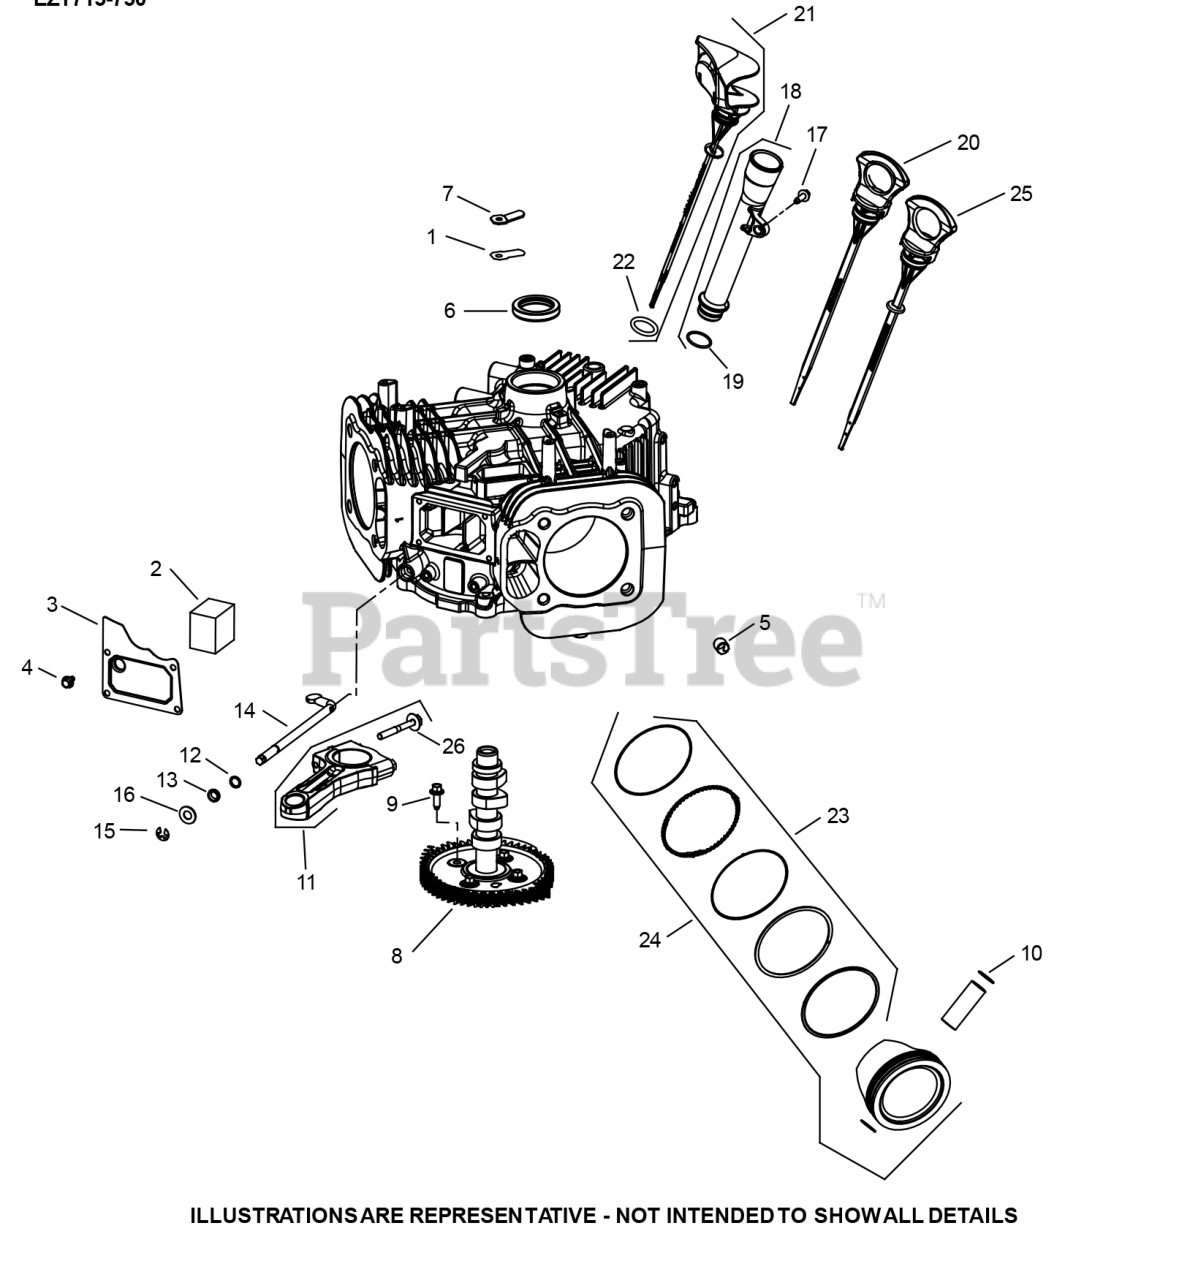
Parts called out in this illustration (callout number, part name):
1	BREATHER REED
2	BREATHER FILTER
3	COVER-BREATHER FILTE
5	PIN-SPLIT DOWEL
7	RETAINER-BREATHER
8	CAMSHAFT ASSEMBLY
10	RETAINER-PISTON
11	CONNECTING ROD ASSEMBLY
12	WASHER-1/4 FLAT
14	CROSS CARBURETOR SHAFT KIT
15	GOVERNOR SHAFT RETAINER CLIP
16	WASHER-9MM FLAT
17	THREAD FORMING SCREW
18	DIPSTICK TUBE
22	O-RING DIPSTICK
23	RING SET(STD)STYLE B-1.2mm Tp RING THICK
23	RING SET(.08)STYLE B-1.2mm Tp RING THICK
23	RING SET(.25)STYLE B-1.2mm Tp RING THICK
23	RING SET(.50)STYLE B-1.2mm Tp RING THICK
24	PISTON KIT (STD)
24	PISTON KIT (+0.08)
24	PISTON KIT (+0.25)
24	PISTON KIT (+0.50)
